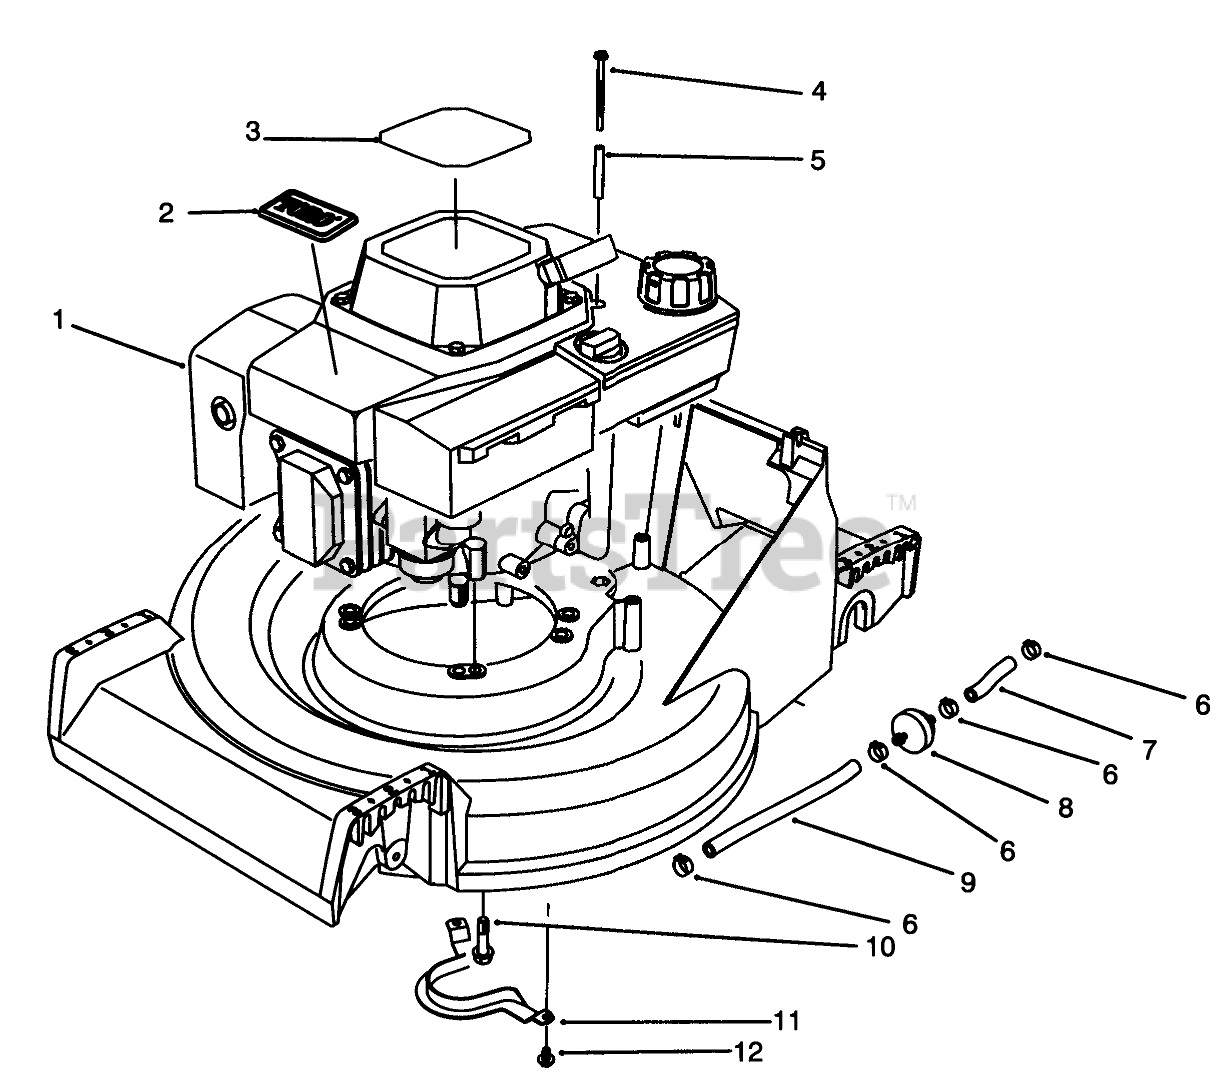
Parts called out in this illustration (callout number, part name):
1	ENGINE ASSY BBC OHV SU
2	TORO LOGO PLT
3	DECAL-HV INT'L
4	THRD FORMING SCREW
5	TUBULAR SPACER
6	CLAMP-FUEL LINE
7	LINE-GAS
8	FILTER-FUEL
9	HOSE-FUEL
10	SCREW-HWH
11	Guide-Belt
12	SCREW-HWHTF
